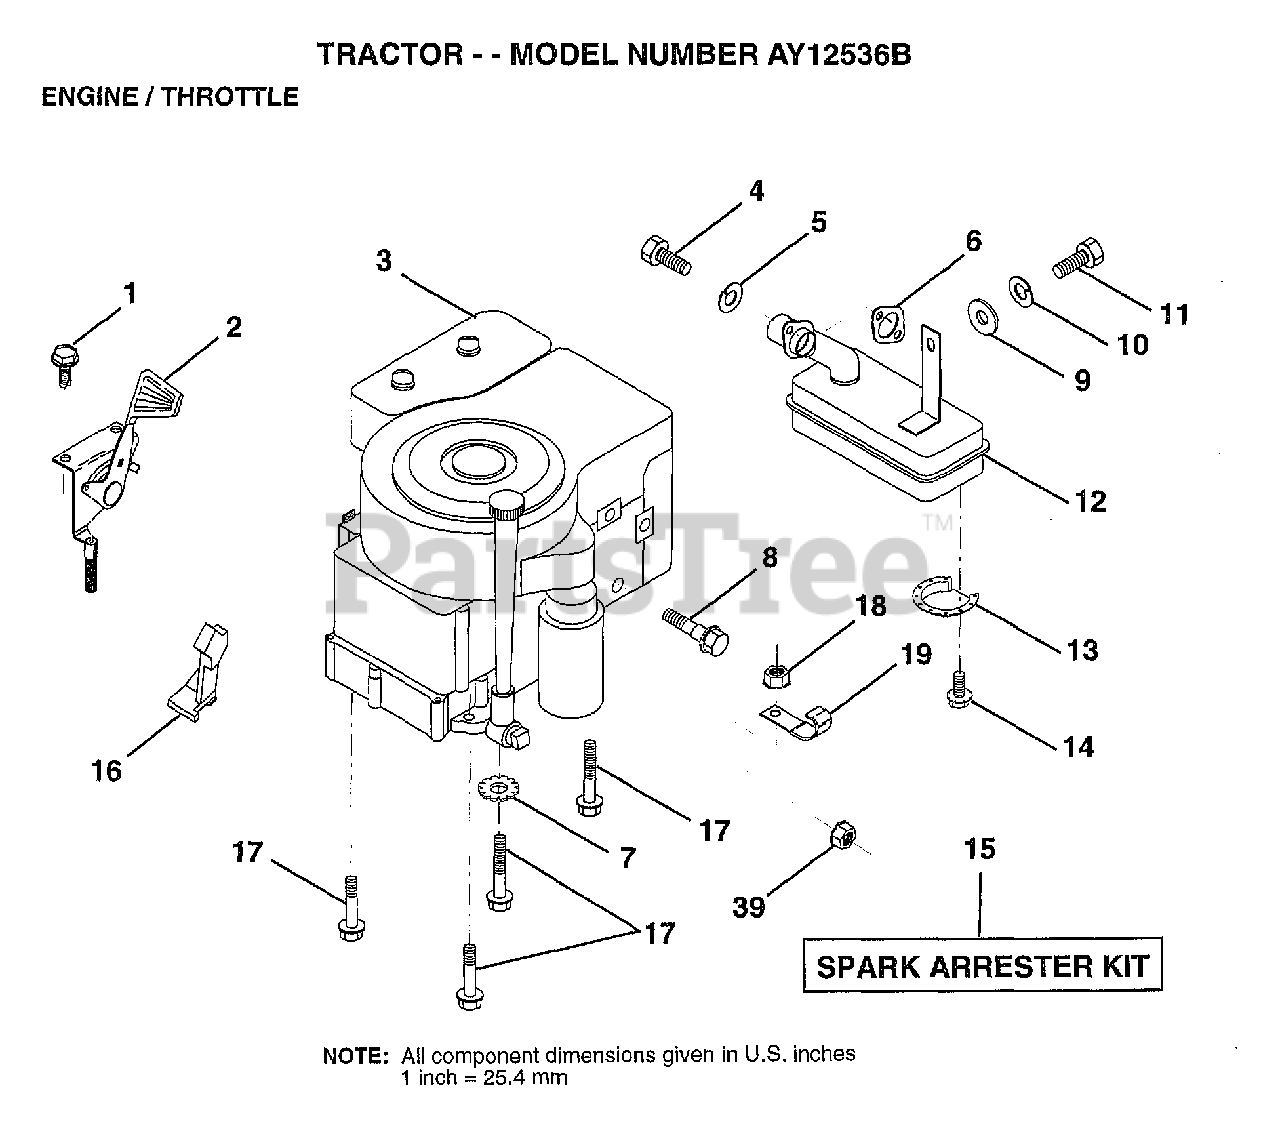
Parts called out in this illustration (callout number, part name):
1	SCREW.1/4-20X1/2
4	SCREW
5	LOCKWASHER
6	GASKET ENG 1 313 LD TIN PLATED
7	LOCKWASHER
8	BOLT T
10	LOCKWASHER
12	MUFFLER
13	DEFLECTOR.222573
16	"STOP,DASH THROTT"
17	SCREW LT
18	NUT
19	CLIP T
39	NUT
